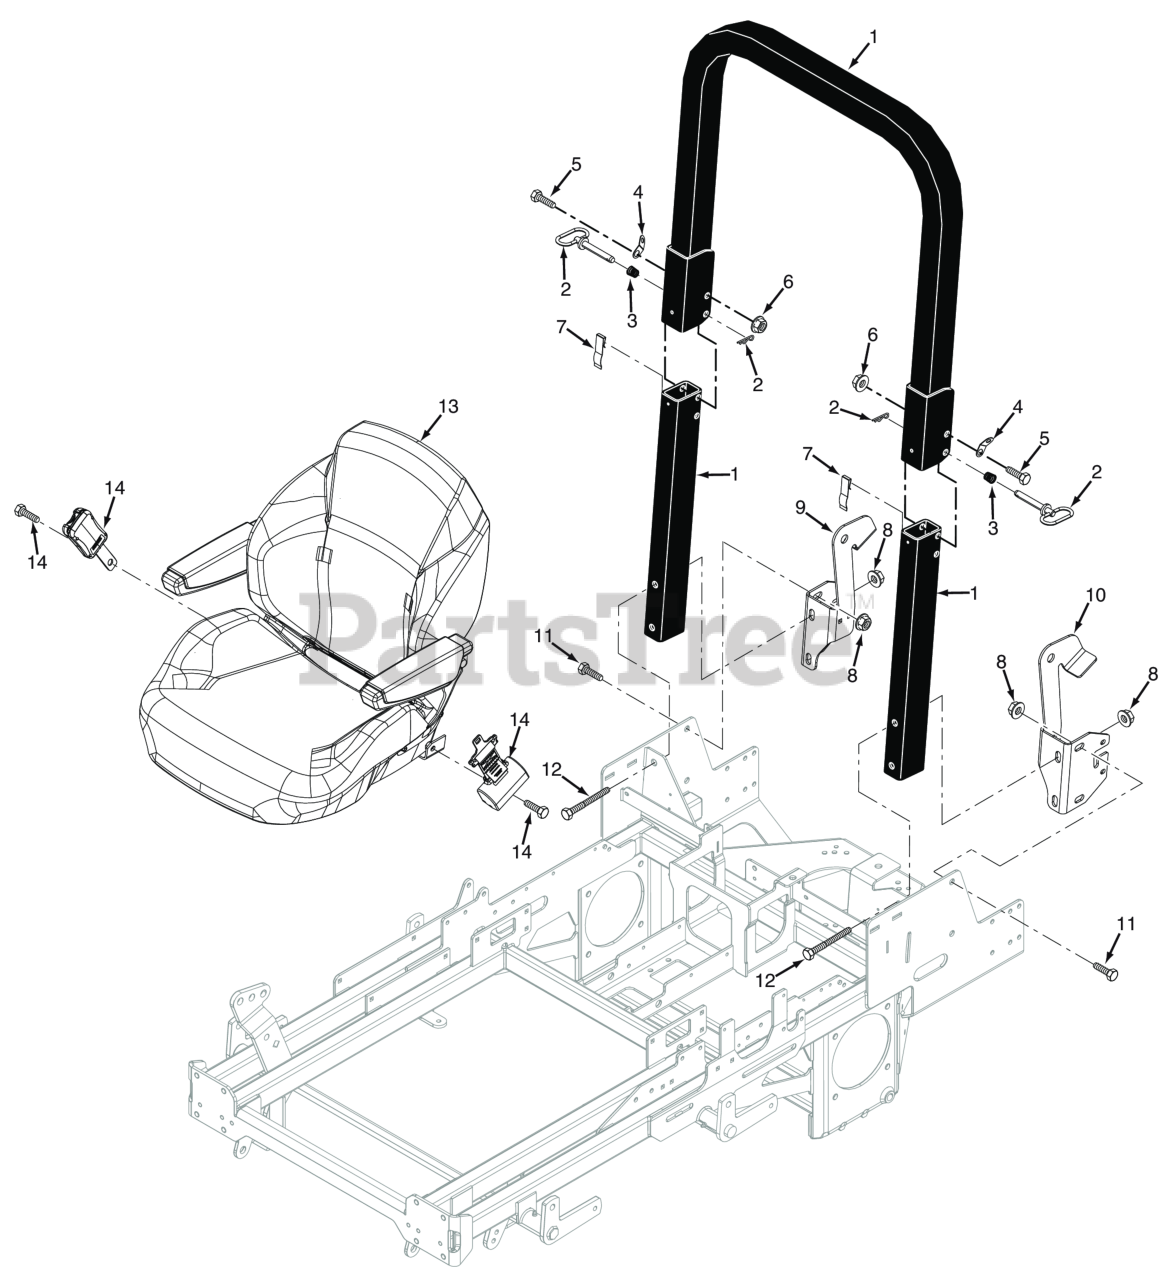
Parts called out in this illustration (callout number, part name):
1	ROPS, Foldable SCZ
2	Pin Assembly, ROPS Hinge
3	Spring, ROPS
4	Clip, ROPS
5	Bolt, Hex Head, 1/2-13 x 3-1/4"
6	HEX LOCKNUT, ELASTIC STOP, 1/2-13
7	Spring, ROPS Anti-Rattle
8	Nut, Elastic Stop 1/2-13, (STT-52 & STTII-52)
9	ROPS Mount, RH, 29CV-EFI
10	ROPS Mount, LH, 29CV-EFI
11	Bolt, Hex Head 1/2-13 x 1-1/4"
12	Bolt, Hex Head 1/2-13 x 4-1/4"
13	Seat Assembly (INCL 14)
14	Seat Belt Kit, Retractable - SCZII
